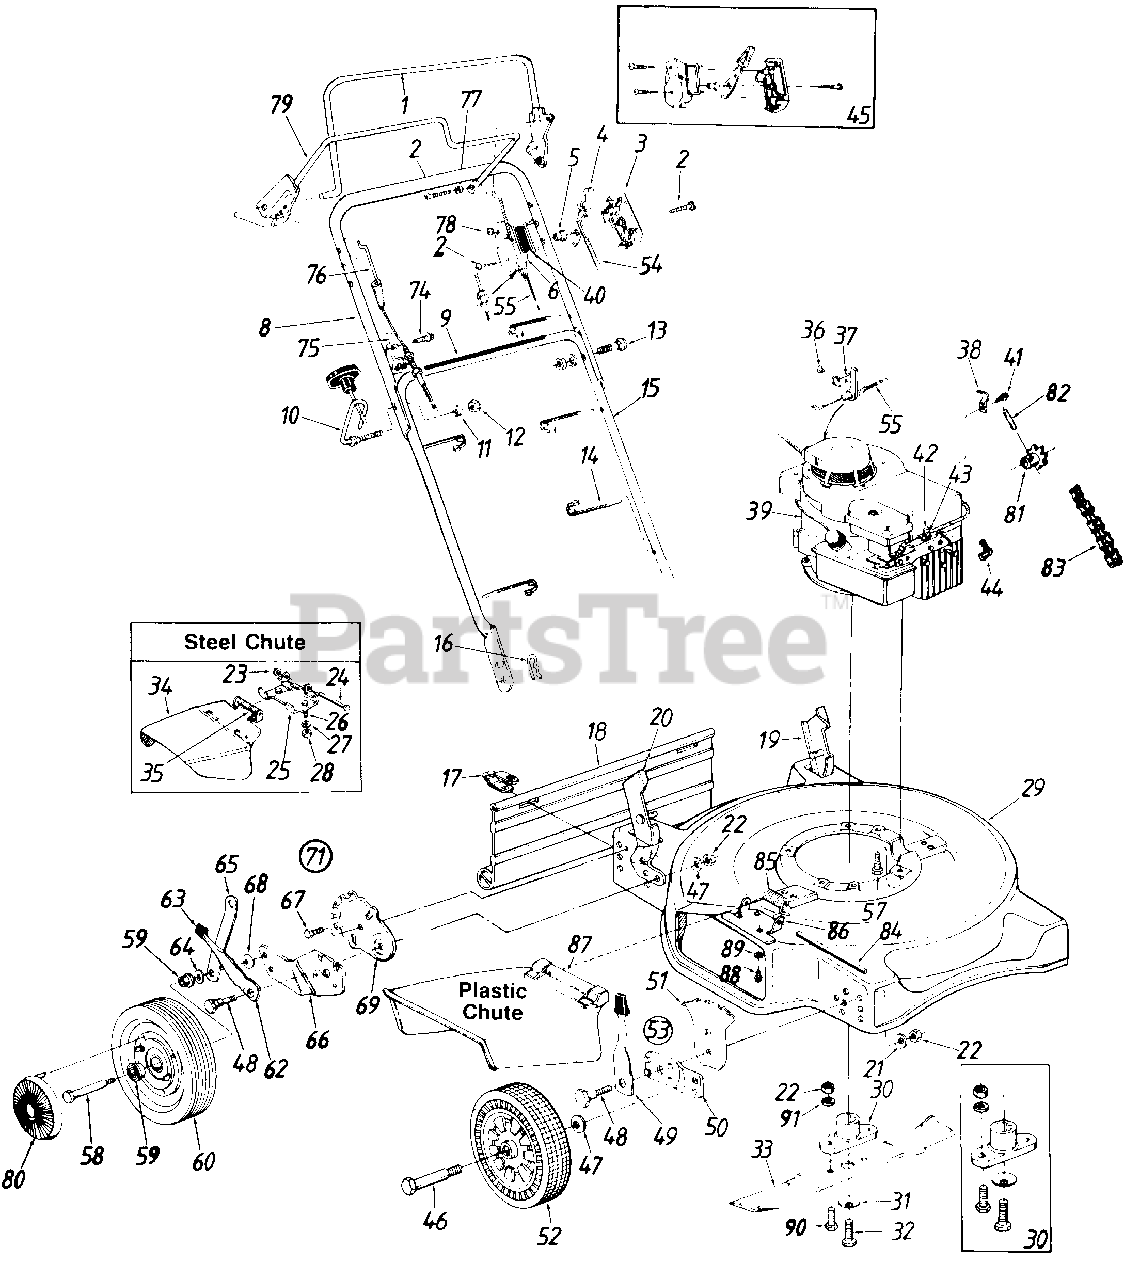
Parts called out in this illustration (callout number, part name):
1	Control Handle Ass'y.
2	Truss Mach. Scr. #12 x 1.5"
3	Control Panel Half
4	Throttle Control Lever
5	Control Disc Pin
6	Clutch Panel Half
8	Upper Handle (Painted)
9	Instruction Label-Handle
10	Rope Guide Bolt
11	L-Wash. 5/16" I.D.
12	Hex Nut 5/16-18 Thd.
13	Curved Carriage Bolt 5/16-18 x 1.38" Lg.
14	Cable Tie
16	Hairpin Cotter
17	Hinge Clip
18	Rear Flap
19	Handle Bracket Ass'y.-L.H.
20	Handle Bracket Ass'y.-R.H.
21	Bell-Wash. .39" I.D. x 1.38" O.D.
22	Hex Nut 3/8-16 Thd.
23	Push Cap 1/4" Rodt
24	Pivot Pint
25	Adapter Platet
26	Hex Bolt 1/4-20 x .50" Lg.t
27	L-Wash. 1/4" I.D.t
28	Hex Nut 1/4-20 Thd.t
30	Blade Adapter Kit
31	Blade Bell-Wash. .39" I.D. x 1.12"
32	Hex Bolt 3/8-24 x 1.5" Lg.
33	22" Blade
34	Chute Deflector Ass'y
35	Torsion Spring
36	Pop Rivet
37	Cable Bracket
38	Cable Clamp
39	Engine
40	Control Label-Throttle
41	Hex B-Tap Scr. #10 x .38"
42	Cable Clamp
43	Hex AB-Tap Scr. #8 x 38" Lg.
44	Spark Plug Boot
45	Kit-Control Housing Comp.
46	Front Axle Bolt
47	Bell-Wash. .400" I.D. x .88"
48	Shld. Bolt .50" Dia. x .357"
49	Spring Lever Ass'y. w/Knob
51	Height Adj. Plate
52	Wheel Ass'y. Comp.
53	Height Adj. Ass'y. Comp.-R.F.
53	Height Adj. Ass'y. Comp.-L.F.
54	Throttle Wire-53"
55	Control Cable-39"
57	Hex L-Wash. HD. Bolt 3/8-16 x 1.0" Lg.
58	Rear Axle Bolt
59	Fl. Ball Brg. 1/2" I.D.
60	Rear Wheel Ass'y. Comp.
62	Spring Lever
63	Spring Lever Knob
64	Fl-Wash. .531" I.D. x .93"
67	Hex AB-Tap 1/4-.62" Lg.
68	Bell-Wash. .380" l.D. x .88"
69	Index Plate
71	Rear Height Adj. Ass'y.-R.H.
74	Hex Wash. AB-Tap Scr. 5/16 x.75" Lg.
75	Cable Brkt.
76	Clutch Cable w/Spring-32" Lg.
77	Spacer .23" I.D. x .30" O.D.
78	Spr.-Wash. .206" I.D. x .448
79	S.P. Bail Ass'y.
80	Hub Cap
81	10 Tooth Sprocket Ass'y.
82	Spring Pin Spir. 1" Lg.
83	#48 Chain 1/2" Pitch x 50 Links-Endless
84	Hinge Pin
85	Torsion Spring
86	Adapter Plate
87	Chute Deflector Ass'y.
88	Hex Self-Tap Scr. 1/4-20 x .5" Lg.
89	Bell-Wash. 1/4" I.D.
90	Hex Bolt 3/8-16 x 1" Lg.
91	L-Wash. 318" I.D.*
